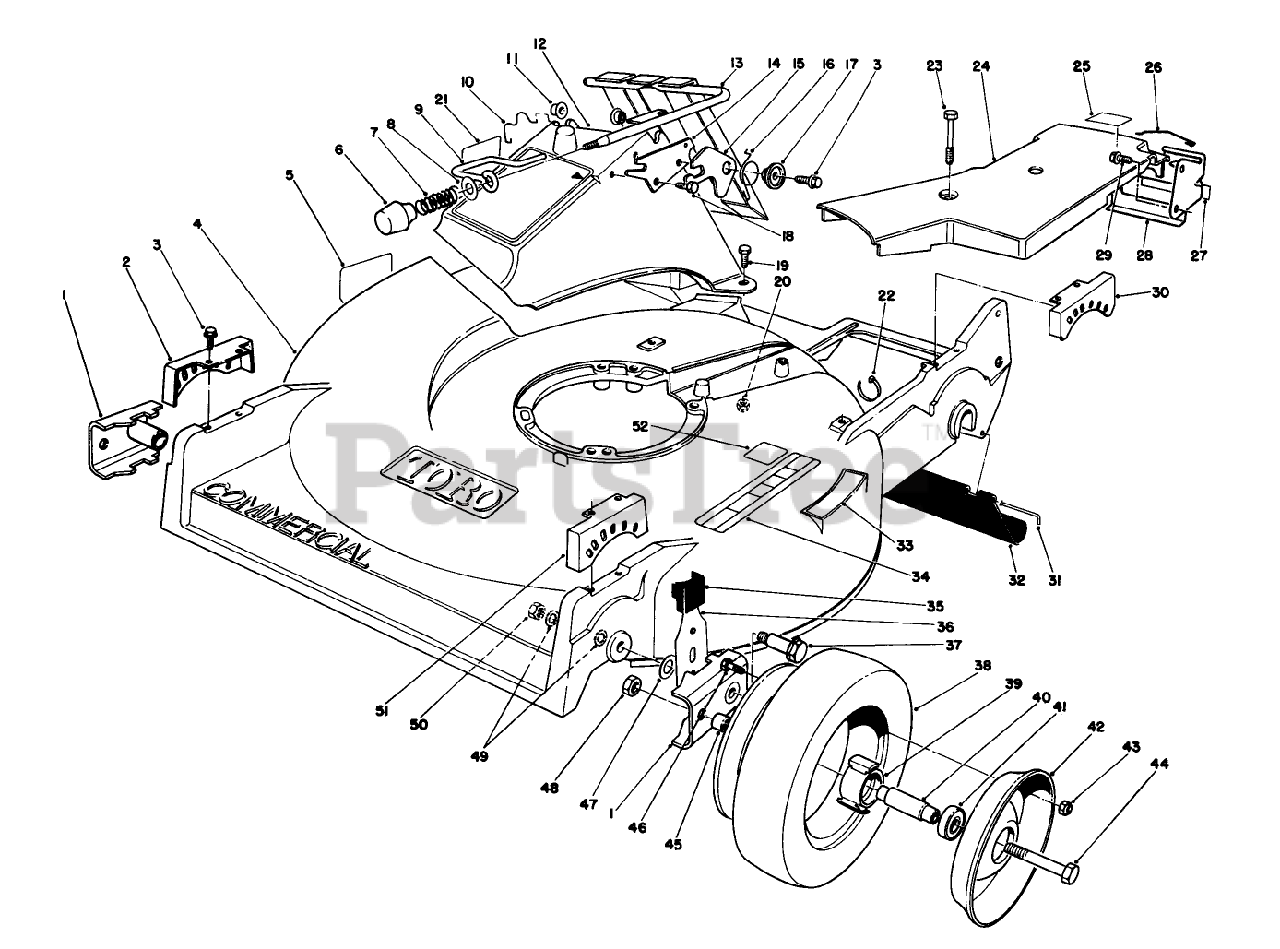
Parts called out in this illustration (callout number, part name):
1	ARM-PIVOT, FRONT
2	QUADRANT-FRONT, RH
3	SCREW-HWHTF
7	COMPRESSION SPRING
8	WASHER-FLAT
9	DOOR LATCH
10	DOOR RETAINER
11	BUSHING-NYLON
12	DISCHARGE CHUTE *B
14	DOOR LATCH PLATE
15	SAFETY LATCH
16	TORSION SPRING
17	DOOR SPACER
18	SCREW-HWH
19	SCREW-HH
20	NUT-LOCK, NI
22	TIE-CABLE
23	SCREW-HWH
24	COVER-BELT
26	RETAINER-CABLE
27	DECAL-POSITION, GEAR
29	SCREW-HWHTF
30	QUADRANT-REAR, LH
31	ROD-SHIELD
33	DECAL - STEP PAD INT'L
35	KNOB-ARM
36	FRONT SPRING ARM ASM
37	WHEEL BOLT
39	HUB-BEARING
40	SPACER-BEARING
41	BEARING-WHEEL
43	NUT-LOCK, NI
44	SCREW-HH
45	SPACER-WHEEL
46	SCREW-HH
47	WASHER-THRUST
48	NUT-LOCK, CONE
49	WASHER
51	QUADRANT-FRONT, LH
52	Decal-Noise Level
